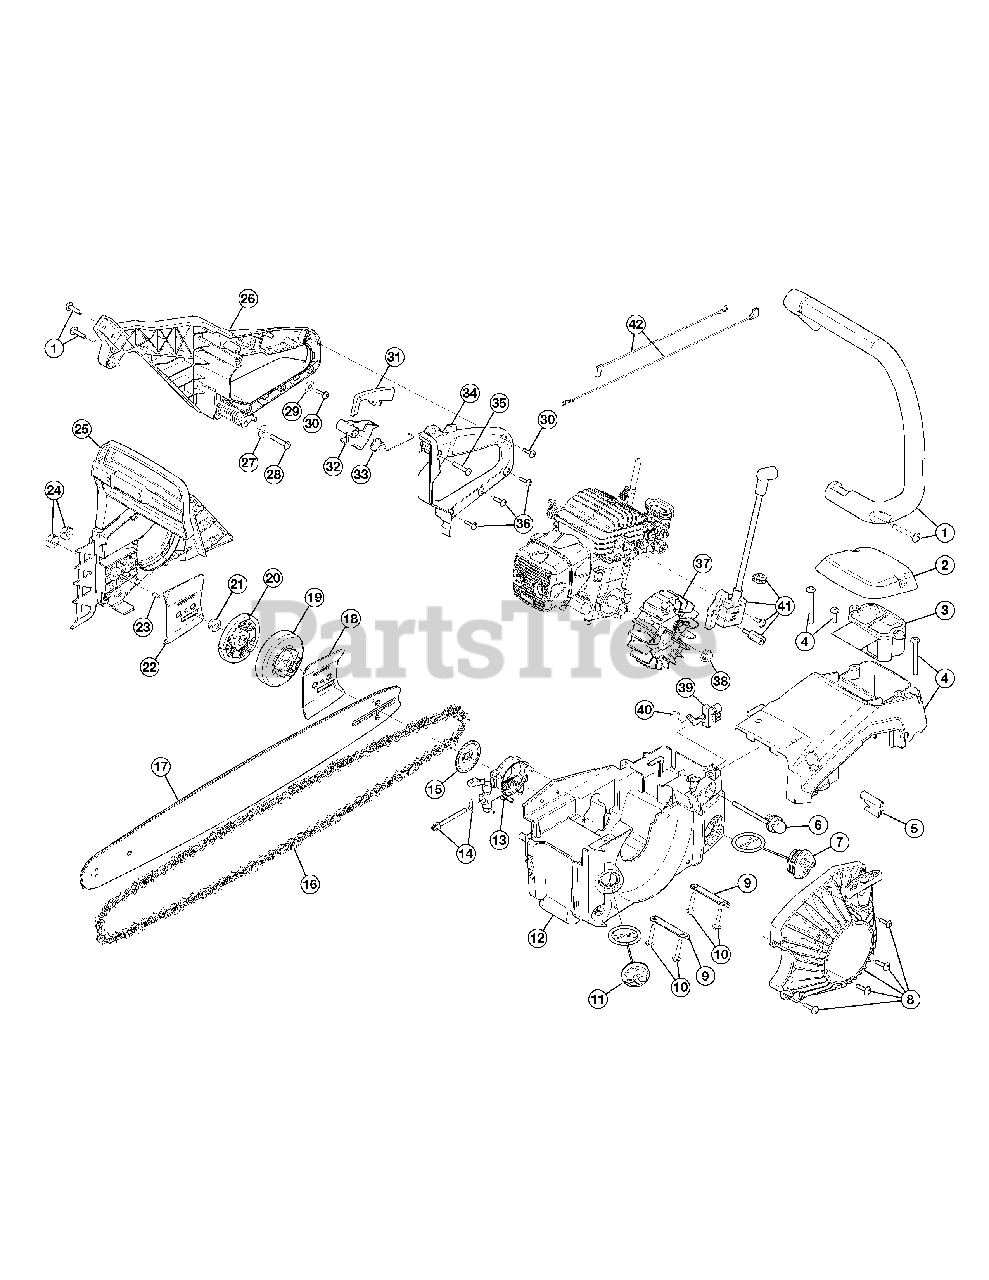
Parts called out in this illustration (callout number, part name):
1	Handle Assembly with Screws
2	Air Cleaner Cover Assembly
3	Air Cleaner Assembly
4	Top Cover Assembly (Incl. 5)
6	Primer Bulb Assembly
7	Fuel Cap
8	Starter Housing Assembly
9	Engine Mount Plate Assembly (Incl. 10)
10	Engine Mount Screw
11	Oil Cap
12	Housing Assembly (Incl. 6, 7 & 11)
13	Oil Pump Assembly
14	Tension Screw & Nut Assembly
15	Oil Pump Shield
16	18" Chain
17	Chain Guide Bar
18	Inner Guide Plate
19	Clutch Drum Assembly
20	Clutch
21	Clutch Nut
22	Outer Guide Plate
23	Guide Plate Screw
24	Chain Guide Bar Nut
25	Chain Brake Assembly
26	Rear Handle Assembly
27	Grip Anti-vibration Washer
28	Grip Anti-vibration Screw
29	Throttle Clamp Washer
30	Throttle Clamp Screw
31	Trigger Release
32	Throttle Trigger
33	Trigger Release Spring
34	Rear Handle Cover Assembly (with Switch)
35	Upper Grip Screw
36	Lower Grip Screw
37	Flywheel Assembly
38	Flywheel Nut
39	Choke Lever Assembly
40	Choke Rod
41	Module Assembly
42	Ground Wire
